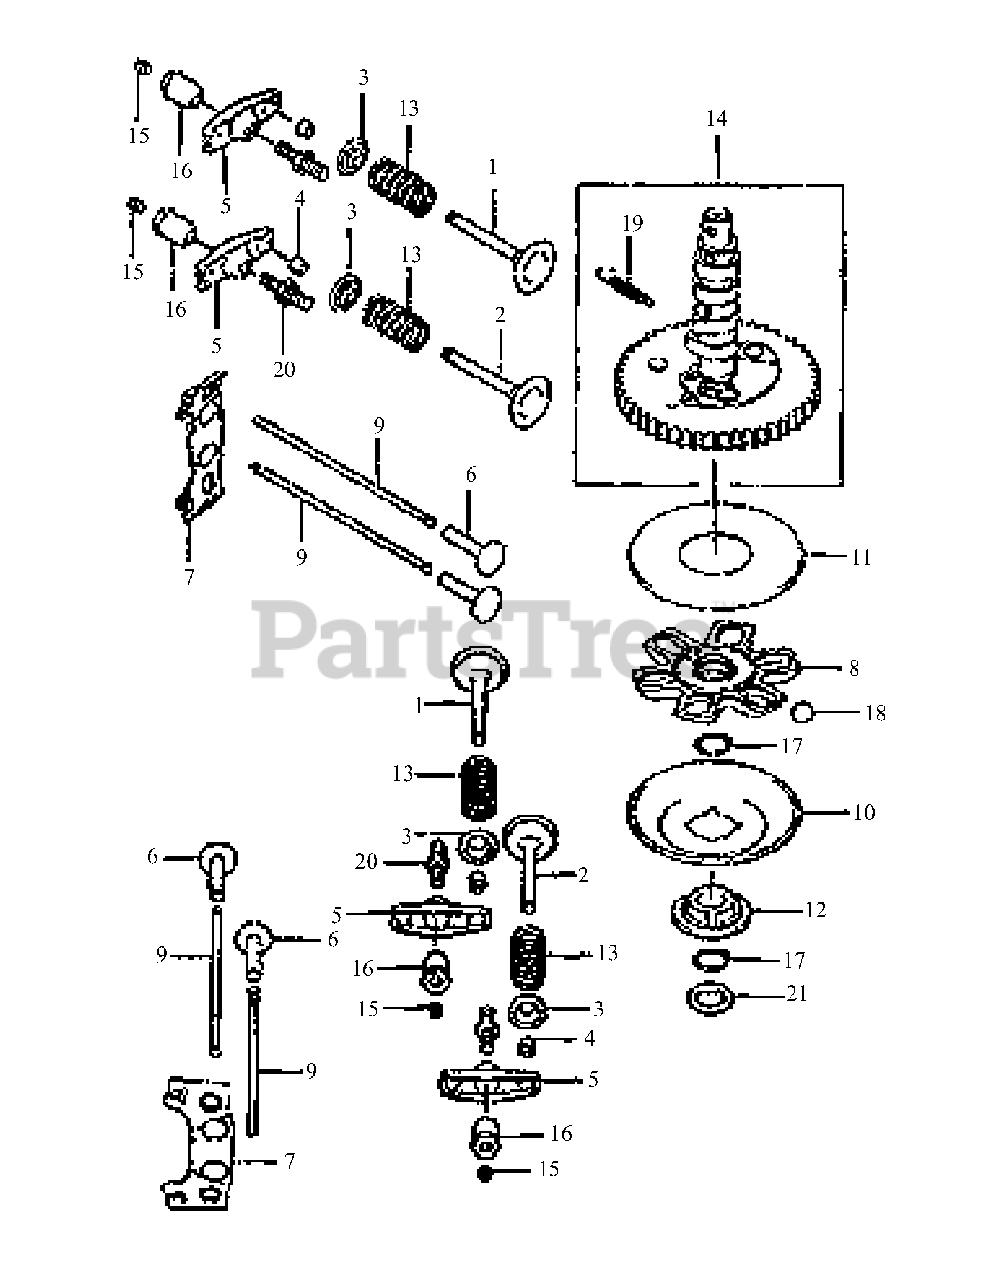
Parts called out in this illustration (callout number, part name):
1	Valve, Intake
2	Valve, Exhaust
3	Retainer, Valve Spring
13	Spring, Valve
17	Ring, Snap
18	Ball
19	Spring
